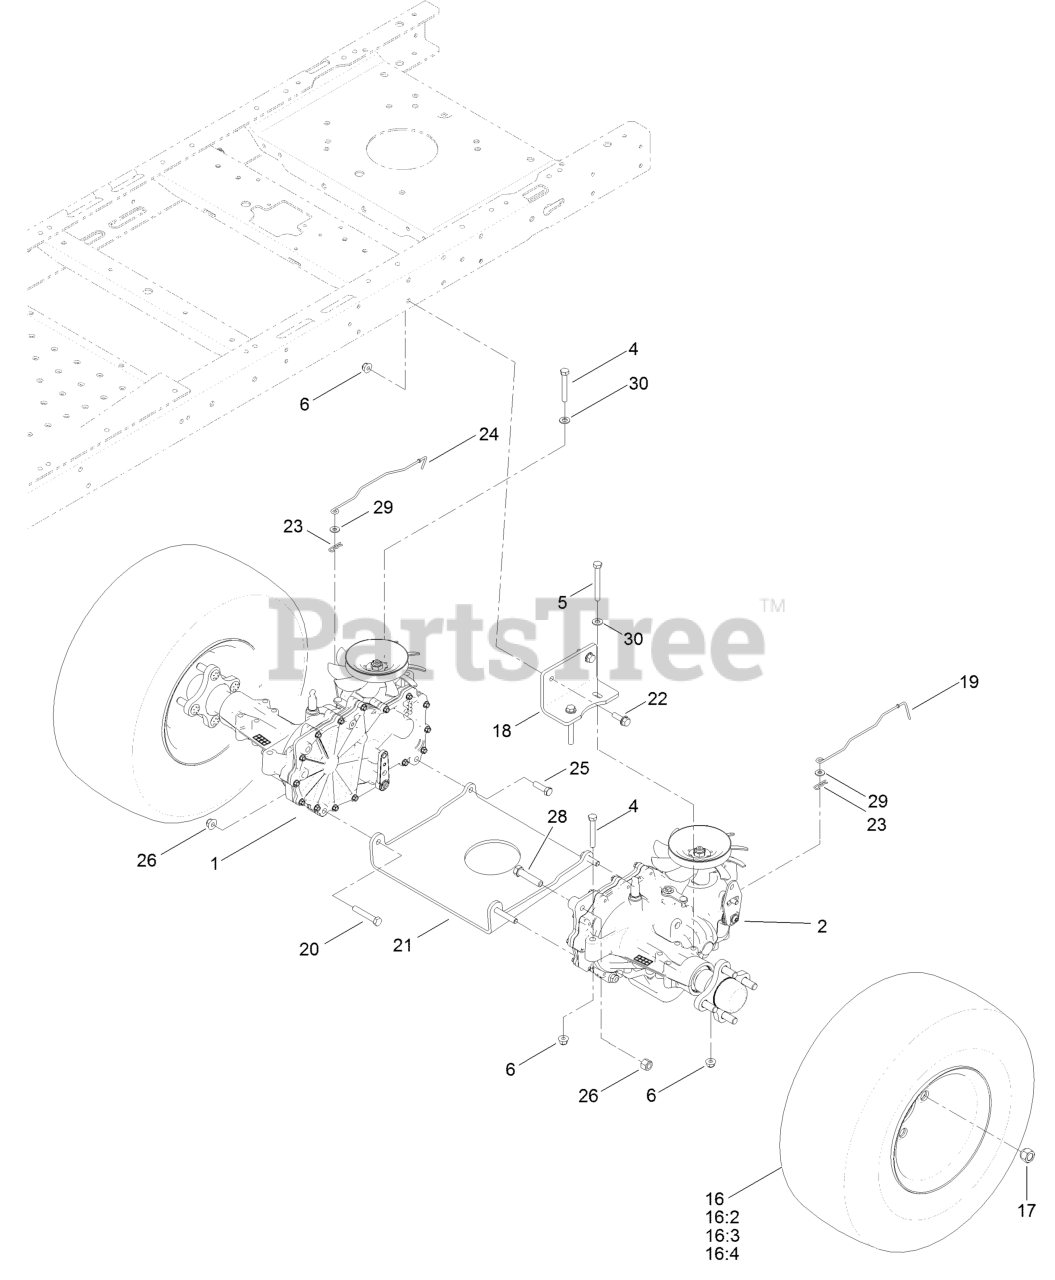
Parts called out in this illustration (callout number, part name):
1	RH HYDRO TRANSMISSION ASM
2	LH HYDRO TRANSMISSION ASM
4	SCREW-HH
5	SCREW-HH
6	NUT-HF, NI
16	2 PLY TIRE AND WHEEL ASM
16:2	TIRE-2 PLY
16:3	Stem-Valve
17	NUT-LUG
18	MOUNT-HYDRO
19	ROD-BYPASS, LH
20	SCREW-HH
21	PLATE-CROSS, HYDRO
22	SCREW-HHF
24	ROD-BYPASS, RH
25	SCREW-HH
26	NUT-HF, NI
28	SCREW-HH
30	WASHER-PLAIN
